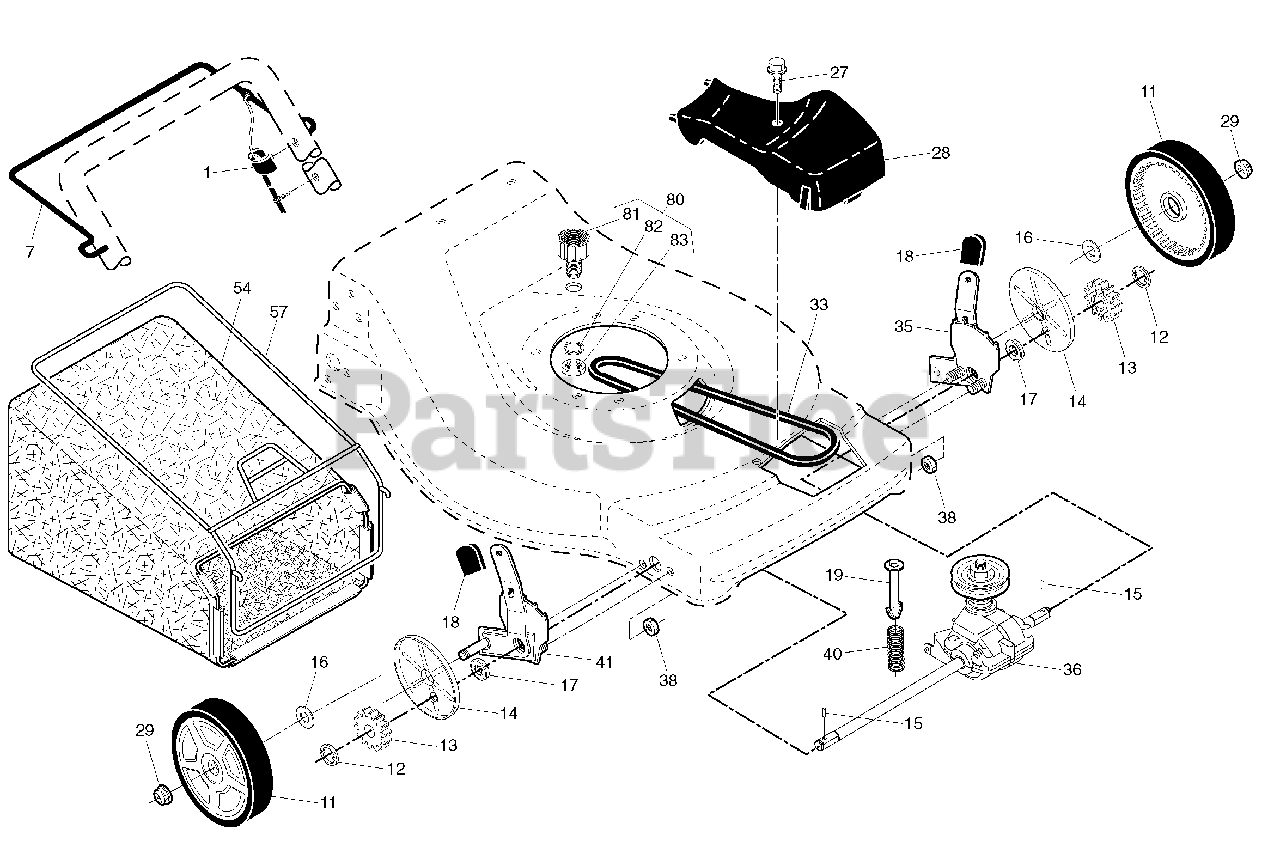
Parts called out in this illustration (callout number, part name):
1	Drive Control Cable
7	Bar, Drive Control
11	Wheel & Tire Assembly, Front
12	E-Ring
13	Pinion
14	Dust Cover
15	Pawl, Drive
16	Washer, Flat 3/8
17	Bearing, Wheel Adjuster Assembly
18	Selector Knob
19	Retainer, Spring
27	Pan Head Tapping Screw #10-24 x 2-3/4
28	Drive Cover
29	Locknut, Hex
35	Kit, Wheel Adjuster, LH
36	Gear Case Assembly, Complete
38	Locknut 1/4-20
40	Spring
41	Kit, Wheel Adjuster, RH
54	Grassbag Assembly
57	Frame, Grassbag
80	Water Washout Assembly
81	Fitting, Hose, Water Washout
82	Washer, Lock, Internal Tooth
83	Locknut, Hex, with O-Ring
